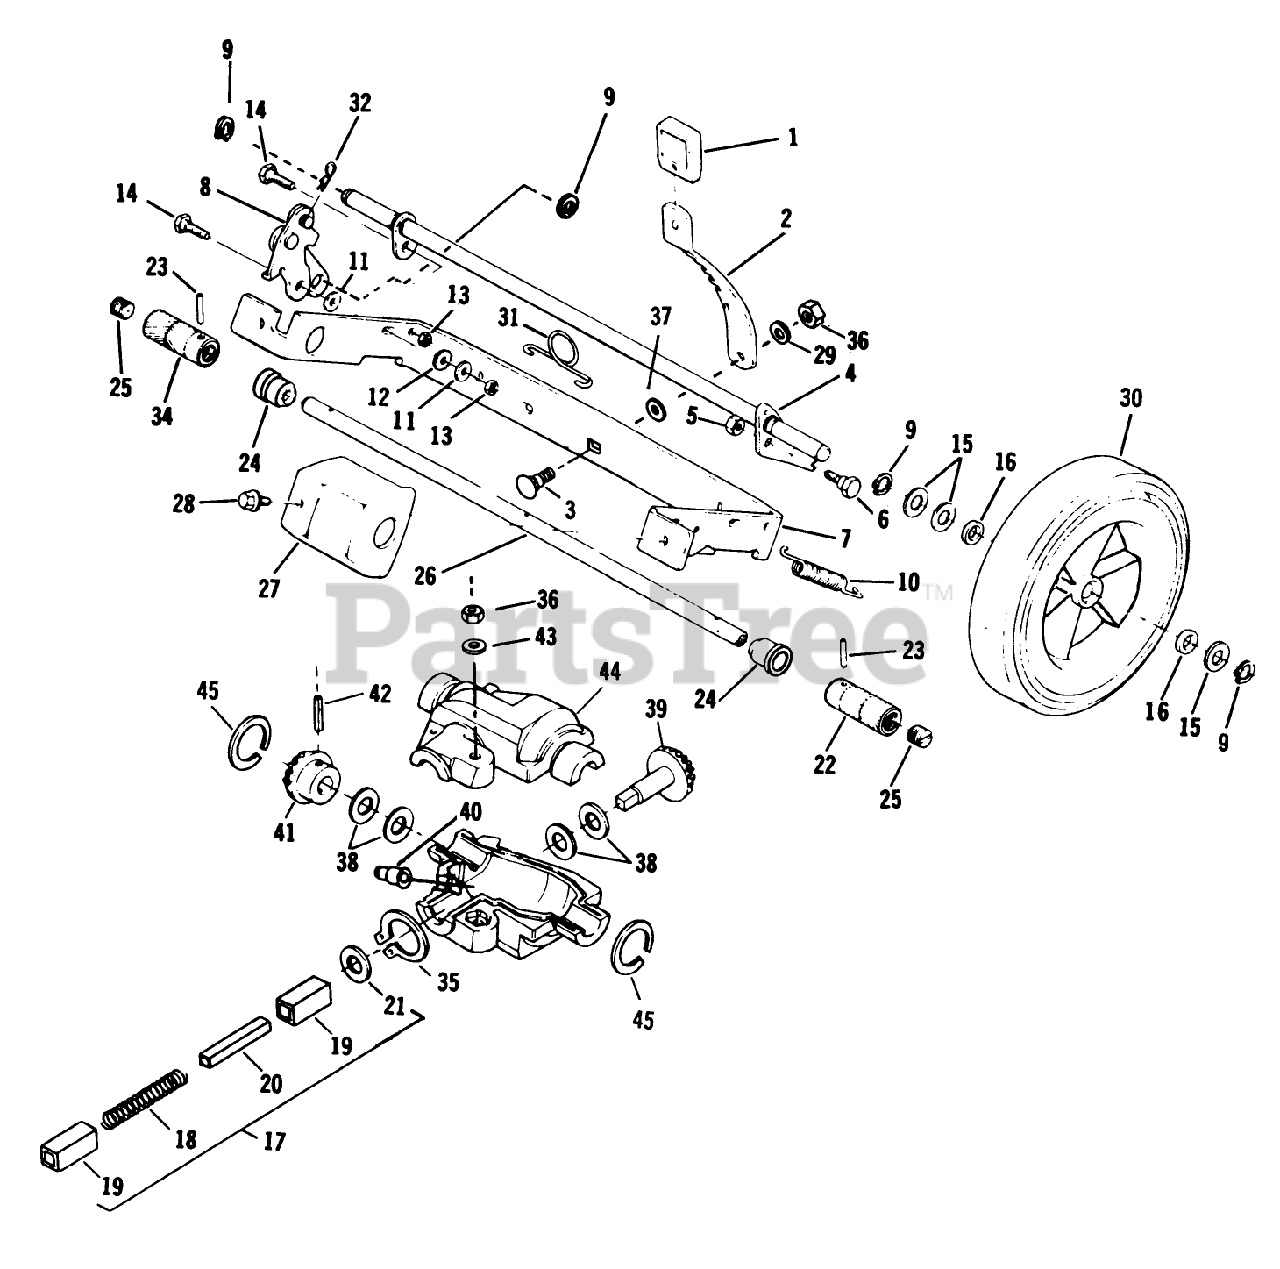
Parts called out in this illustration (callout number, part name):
1	KNOB
2	LEVER
5	LOCKNUT E
6	BOLT RB&W
7	BRACKET *GREEN
9	RET RING
10	SPRING
11	WASHER S
13	STOP NUT
14	BOLT RB&W
15	SPACER
16	WASHER
18	SPRING
19	BUSHING BKWY
21	THRUST WASHER
22	ROLLER (LEFT) VS
22	ROLLER-LH
23	PIN
24	SLEEVE &BEARING AY
25	GREASE PLUG
26	DRIVE SHFT TAG AY
27	GUARD
29	WASHER S
30	WHEEL & TIRE KIT
31	SPRING N.A.S
33	RET RING
34	ROLLER (RIGHT) VS
34	Drive Roller-R.H.
36	LOCKNUT E
37	WASHER SPRING LAR
38	THRUST WASHER
39	GEAR BEST
40	ZERK FITTING
41	GEAR ADVANCE
42	ROLL PIN
43	WASHER F
44	GEARCASE AY-SERV
